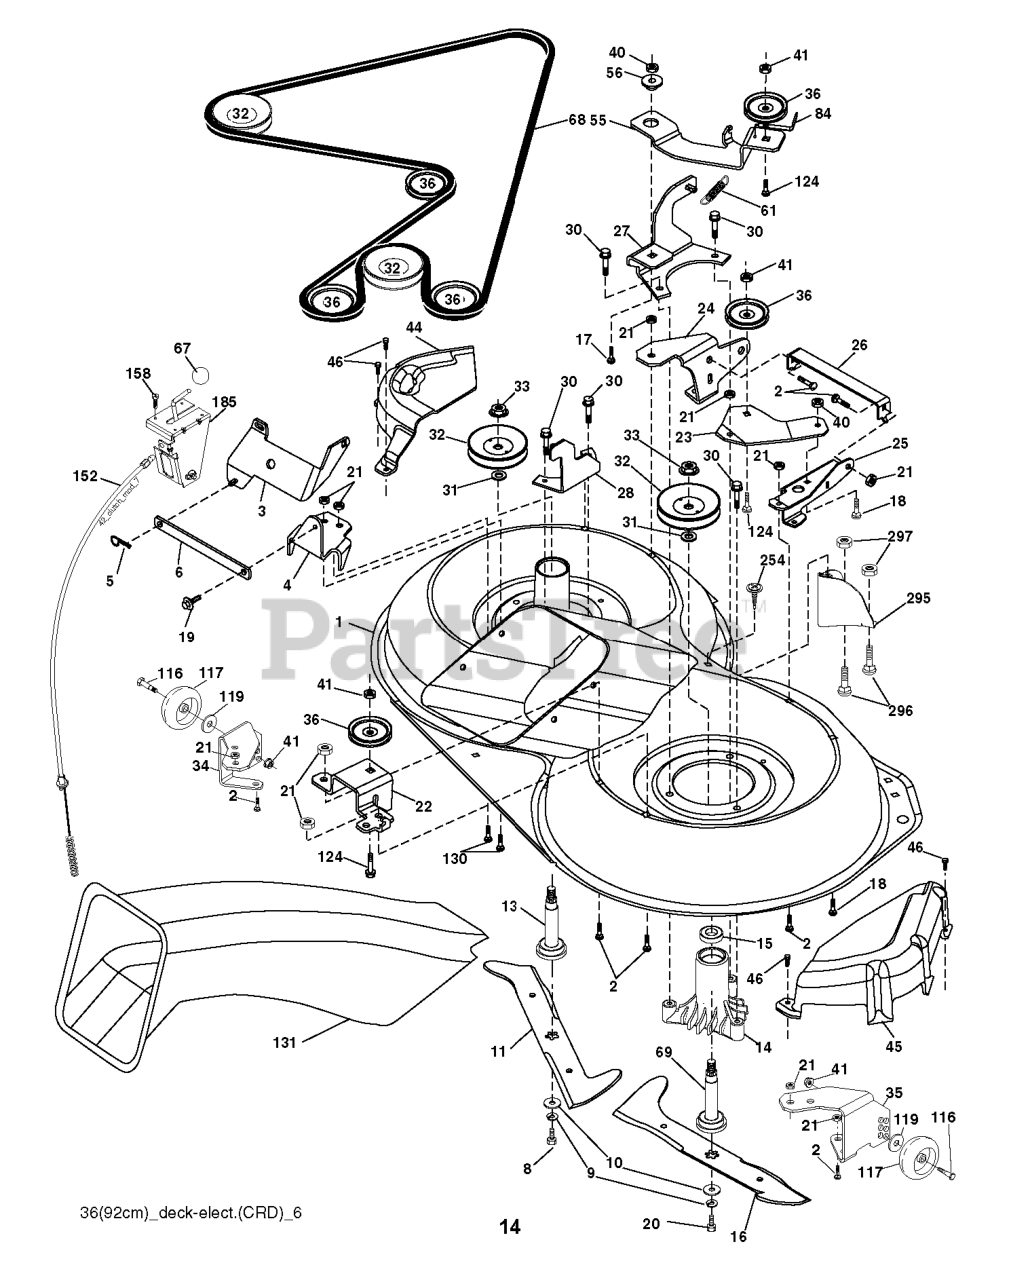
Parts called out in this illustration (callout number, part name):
2	RP BOLT 5/16-18 X3/4 ZN/YEL GR
5	RETAINER-SPRNG RB
6	BAR.SWAY.92.CRD
8	BOLT.3/8-24X1.25 GR8
9	LOCKWASHER
10	WASHER.BLADE
13	SHAFT ASM VENT
14	HOUSING.MANDREL.VENTED (MACHD)
17	BOLT.3/8-14X1.25
19	BOLT SHD 5/16-18
20	BOLT.3/8-24X1.25GR8. LHTHRD
21	LOCKNUT
26	SUPPORT
30	SCREW, WASHER HEAD
31	WASHER.SPACER.MANDREL
32	PULLEY MANDREL
33	NUT.FLANGE.LOCK.TOP
36	PULLEY.IDLER.4.25
41	NUT LOCK FLG 3/8-16 UNC
45	COVER.MANDREL.RH.CRD
46	SCREW.1/4-20X5/8
55	ARM.IDLER.92 CRD.2006
56	SPACER.RETAINER.MOWER
61	SPRING
67	KNOB T (3/8 HOLE)
68	BELT.DRIVE.92CM.CRD.2006
69	SHAFT.ASM.W/LWR.BRG.RH.THREAD
84	KEEPER, BELT IDLER
116	BOLT.SHOULDER.3/8-16X3-5/8.
117	RP WHEEL. GUAGE RALLY
119	WASHER
124	BOLT.3/8-16X1.50
130	BOLT.CARR.SQNK.5/16-18UNC.X3/4
131	CHUTE BAGGER
158	SCREW
185	HEAD ASM. CABLE CLUTCH
254	SCREW 3/8-16X1
296	BOLT
297	NUT CENTERLOCK
